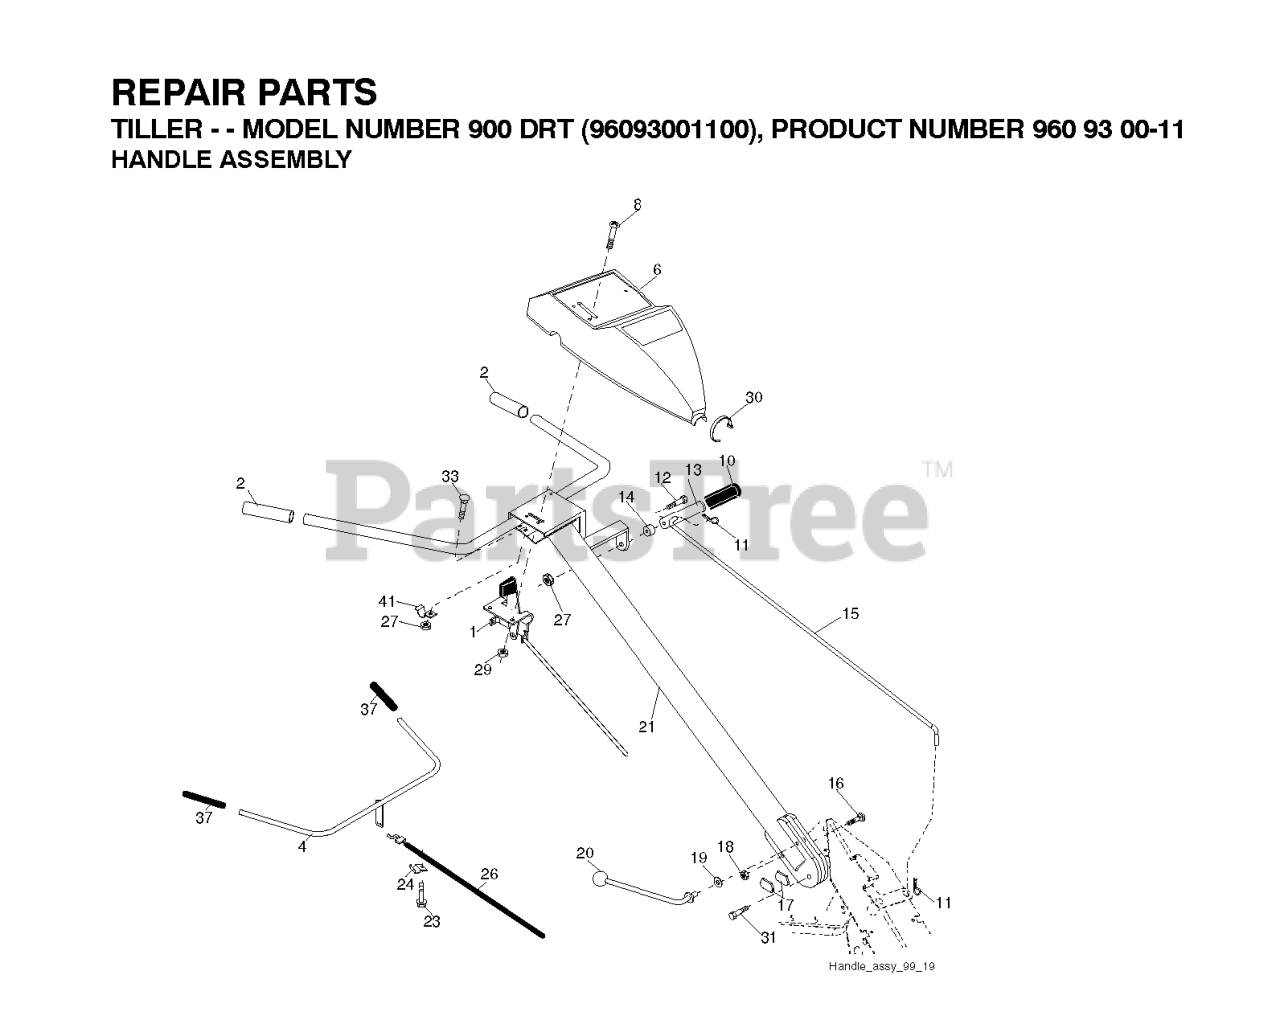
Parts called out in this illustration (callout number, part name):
1	THROTTLE.CONTROL.RT.INTEK.50
2	GRIP.1X5.06
4	CONTROL BAR ASSY
6	RP CONTROL PANEL
8	SCREW.PNHD.10-24
10	GRIP T
11	RETAINER M
12	SHOULDER BOLT ST
13	HANDLE.SHIFT.TILLER
14	GROMMET.RUBBER.CRT.TILLER
15	SHIFT ROD CRT
16	BOLT D
17	LOCK.HANDLE.CRT
19	WASHER CRT
20	LEVER.LOCK.CRT
21	REPL BY 532 1805-17
23	TAPPING SCREW
24	CONDUIT.CLIP.PLATED
26	CABLE.CLUTCH
27	NUT T
29	NUT **
30	TIE CABLE CRT
31	BOLT.PIVOT
37	GRIP BAR CRT(1)
41	CLAMP.BAR.CRT.BLACK
